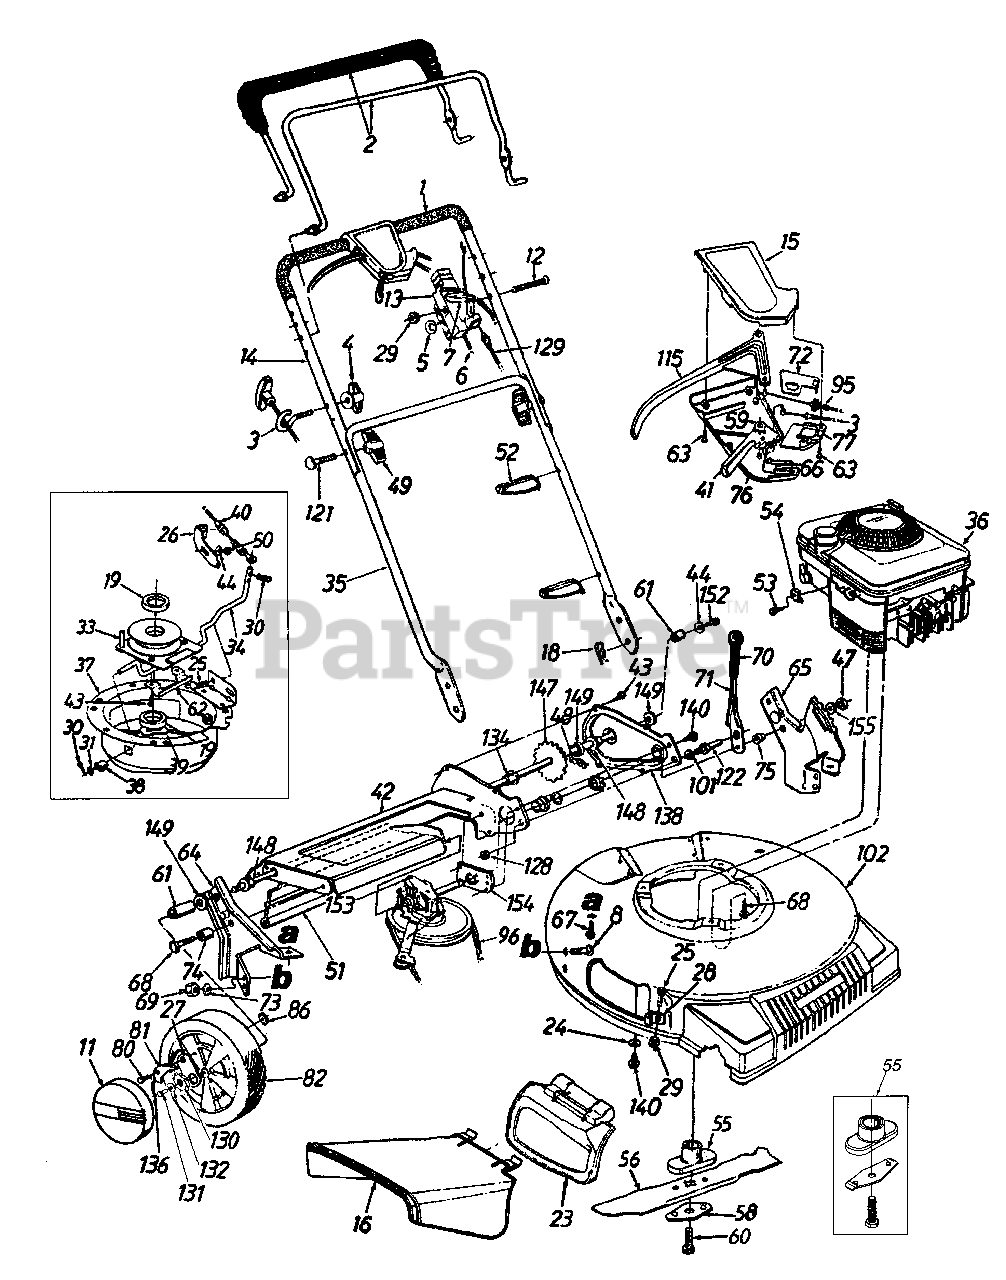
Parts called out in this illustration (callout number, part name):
1	Grip
3	Rope Guide
4	Handle Knob 1/4-20 Thd.
5	Curved Spring Wash. .66" I.D.
6	Throttle Wire-55" Lg.
7	Throttle Lever
8	Carriage Bolt 5/16-18 x .62" Lg.
11	Hub Cap
12	Oval C-Sunk Mach. Scr.
13	Throttle Body
15	Upper Control Housing
16	Side Chute Deflector
18	Internal Cotter Pin 5/16" Dia.
19	Spacer .88" I.D.
23	Mulch Plug Ass'y.
24	Bell-Wash. .265" I.D. x .75" O.D.
25	Carriage Bolt 1/4-20 x .5" Lg.
30	Cotter Pin 3/32" Dia. x .75"
31	Fl-Wash. .328" I.D. x .68"
33	Pulley Ass'y
34	Shift Rod
36	Engine
39	Wave Washer .88" I.D.
40	6 Spd. Cable
41	6 Spd. Shift Lever
44	Bell-Wash. 1/4" I.D.
47	Hex Patch L-Nut 3/8-24 Thd.
48	#48 Chain .500" Pitch x 38 Links
49	Hand Knob
50	Hex L-Nut 1/4-20 Thd.
51	Rear Flap 4.8" x 17.5" Lg.
52	Cable Tie
53	Hex Wash. Hd. Scr. #10-32 x .62" Lg.
54	Casing Clamp
55	Blade Adapter
56	21" Mulching Blade
58	Blade Bell Support
59	Gear Insert
60	Hex Bolt 3/8-24 x 2.5" Lg. (Gr. 8)
61	Spacer .513" I.D.
67	Screw Tap
68	Hex TT-Tap Scr. 3/8-16
69	Hex Nut 5/16-18 Thd.
71	Height Adj. Lever
72	6 Spd. Rack Cable Brkt.
73	Bell-Wash. 5/16" I.D.
74	Spacer .383" I.D.
75	Shld. Spacer.5" Dia.
76	Lower Control Housing
77	Cable Mounting Cap
80	Shld. Scr. .342" Dia. x .268
81	Pawl-R.H.
82	Wheel Ass'y. Comp. (Gray Rim)
86	Weld Top L-Nut 1/4-20Thd.
95	S.R Cable
96	V-Belt
101	L-Wash. 3/8" I.D.
121	Curved Hd. Bolt 5/16-18 x 2" Lg.
122	Shld. Pin 1.43" Lg.
128	Hex Jam Nut 3/8-24 Thd.
129	Control Cable-39"
130	Ratchet Wheel 1.62" O.D.
131	Cap Screw HH 1/4-20 x .620
132	Bell Washer .265 ID x .75
134	Hex Flange Bearing
136	Spring Nylon
147	Rear Shaft Ass'y. 21.44" Lg.
148	Hex Flange Brg. .506" I.D.
149	Fl-Wash. .531" I.D. x .930"
152	Hex Bolt 1/4-20 x .62" Lg. (Gr. 5)
153	Transmission Comp.(See Breakdown)
155	Fl-Wash. .385" I.D. x .87" O.D.
